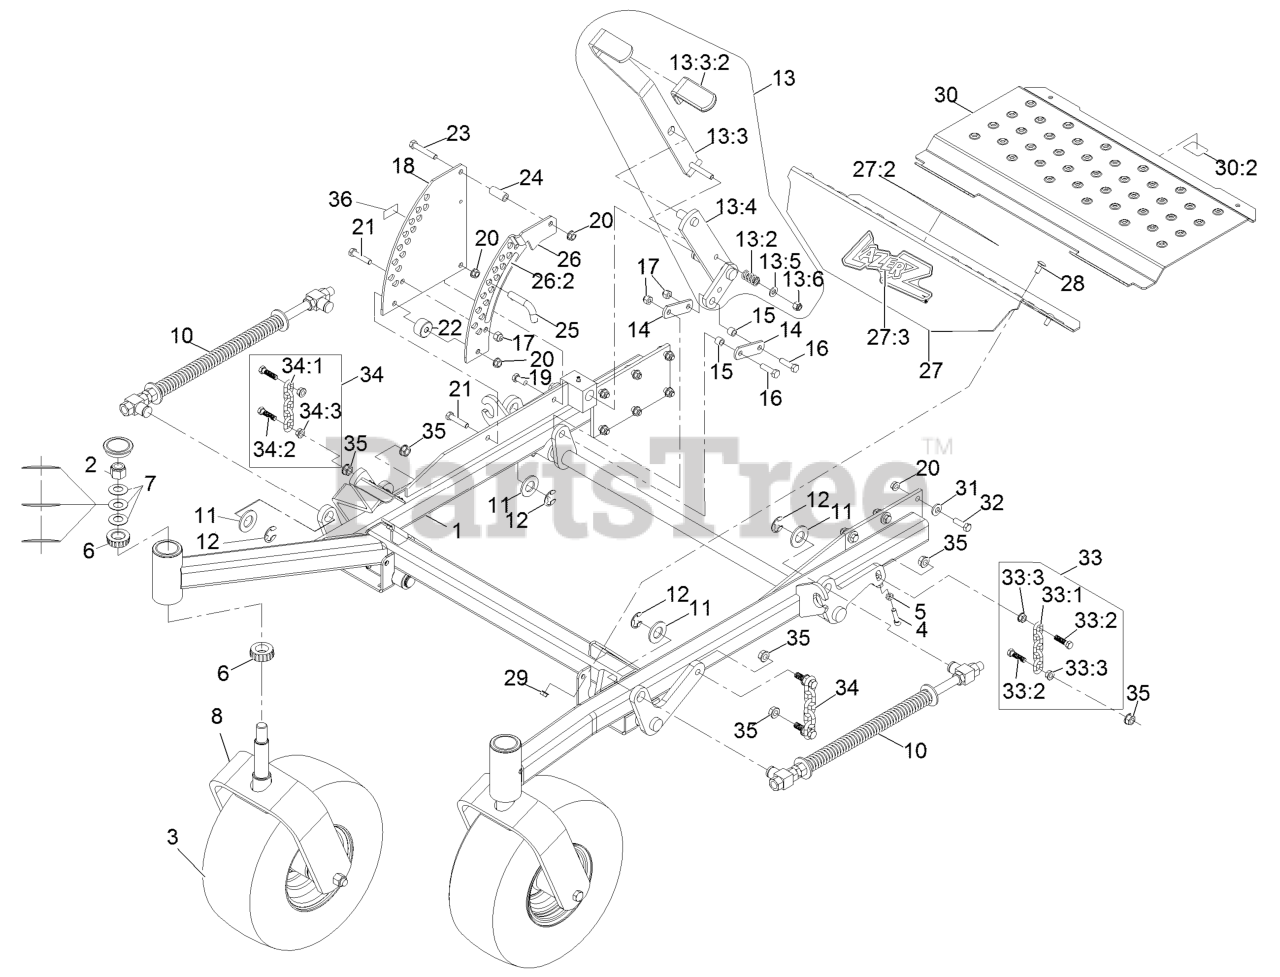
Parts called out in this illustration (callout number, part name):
1	ASM-FRT FRM 72RD
2	NUT-LOCK, NI
3	ASM-WHL AND TIRE
4	SCREW-HSH
5	NUT-JAM
6	Cone-Bearing Tapered Roller
7	WASHER-BELLVILLE
8	WLD-CASTER FORK 15
10	FRONT FRAME SPRING ASM
11	WASHER-FLAT
12	RING-RETAINING, EXT
13	ASM,Deck Lift Handle
13:2	SPRING-COMPRESSION
13:3	LIFT LEVER/GRIP ASM
13:3:2	GRIP-LEVER, LIFT
13:4	WLD,ARM DECK LIFT
13:5	WASHER-FLAT
13:6	NUT-LOCK, NI
14	ARM-LIFT, DECK
15	BUSHING
16	SCREW-HH
17	NUT-LOCK, NI
18	PLATE-DECK LIFT NOTCHED O
19	SCREW-HH
20	NUT-HHF, WHIZ
21	SCREW-HH
22	Stop, Deck Height
23	SCREW-HH
24	BUSHING-LEVER, LIFT
25	PIN-HOC
26	PLATE-LIFT, DECK W/DECAL
26:2	DECAL-HEIGHT OF CUT
27	ASM, FLOORPAN FRONT W/DEC
27:2	DECAL,LAZER MODEL
27:3	DECAL-WARNING, SLOPE
28	BOLT-CARR
30	ASM, FLOORPAN LIFTOUT W/D
30:2	Decal-Guard
31	WASHER-BELLEVILLE
32	SCREW-HH
33	DECK CHAIN ASM
33:1	CHAIN-LIFT, DECK
33:2	SCREW-HH
34	DECK CHAIN ASM
34:1	CHAIN-LIFT, DECK
34:2	SCREW-HH
36	Decal-Patent Ttco.Com
